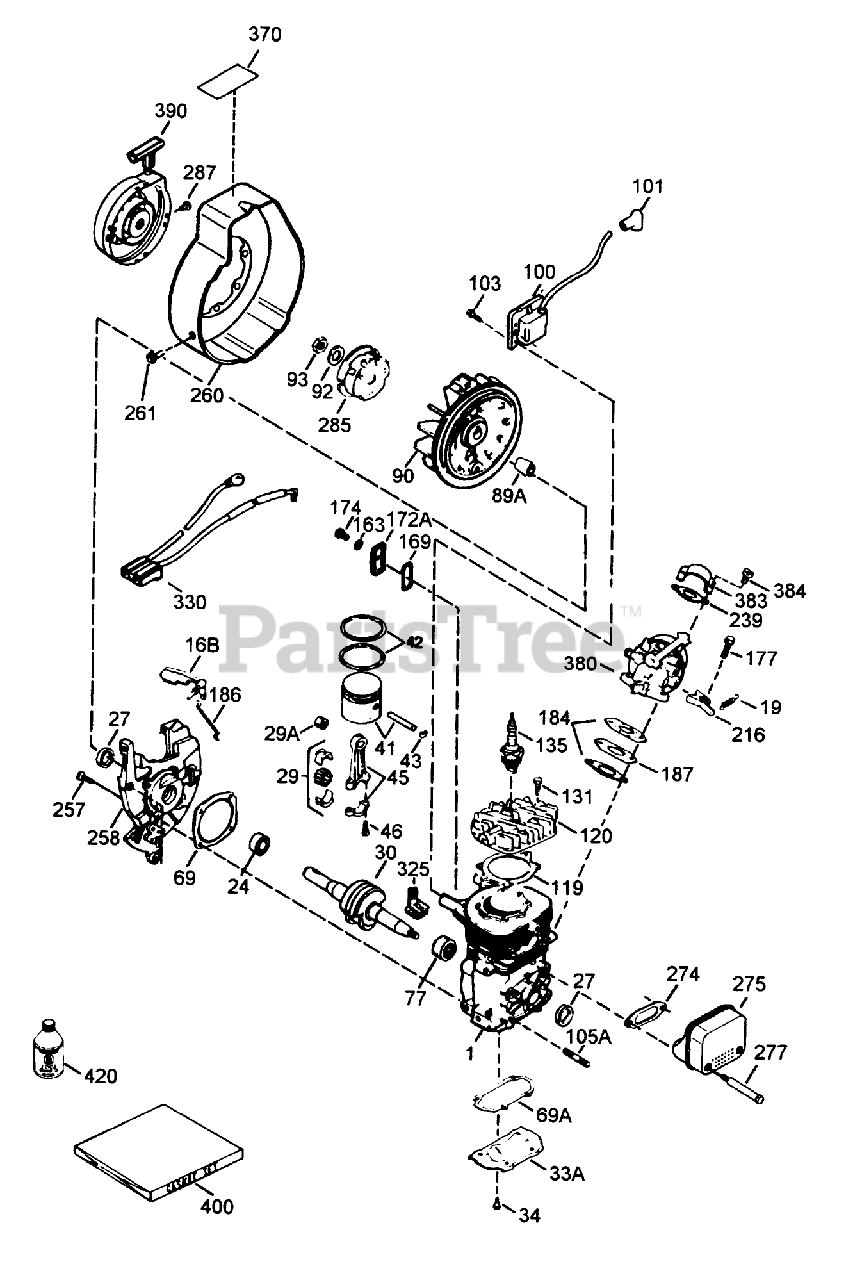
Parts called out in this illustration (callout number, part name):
1	Cylinder (Order Short Block if Replacement is Needed)
16B	Vane-Air
19	Spring-Extention
24	Bearing-Ball
27	Seal-Oil
29	Needle Bearing and Liner Set (37 Needles)
29A	Bearing-Cartridge
30	Crankshaft
33A	Plate-Cover
34	Screw (T-25, 10-24 x 1/2)
41	Piston (Incl. Ref. #43)
42	Ring Set
43	Ring-Retaning
45	Rod Assy.-Connecting (Incl. Ref. #3, 3A 3B)
46	Bolt-Rod, Connecting
69	Gasket-Cover, Cylinder
69A	Gasket-Plate, Cover
77	Bearing-Cartridge
89A	Blade (20 inch)
90	Flywheel
92	Washer-Belleville
93	Nut-Flywheel
100	Solid State
101	Cover-Spark Plug
103	Screw
119	Gasket-Head, Cylinder
120	Head-Cylinder
131	Screw (T-30, 1/4-20 x 3/4)
135	Spark Plug-Resistor (R C J 8Y)
163	Washer
169	Cover-Compression, Release
172A	Cover-Release, Compression
174	Screw (T-25, 10-24 x 1/2)
177	Screw (5/32 Allen, 1/4-20 x 1)
184	Gasket-Carburetor
186	Governor-Link
187	Spacer
216	Lever-Adjusting, Rpm
239	2060A77 WIZARD ROTA
257	Screw (T-30, 1/4-20 x 5/8)
258	Base Assy.-Blower Housing (Incl. Ref. #10)
260	Blower Housing
261	Screw (1/4-20 x 1/2)
274	Exhaust Gasket
275	Muffler (Incl. Ref. #274 277)
277	Screw (1/4-20 x 2-3/4)
285	Cup-Starter
287	Screw (8-32 x 21/64)
325	Clip-Wire
330	Harness-Wire
370	Decal-Warning
380	Carburetor (Incl. Ref. #184A)
383	Baffle-Carburetor
384	Screw
390	Rewind Starter
400	Gasket Set
420	2-Cycle Oil (8oz)
